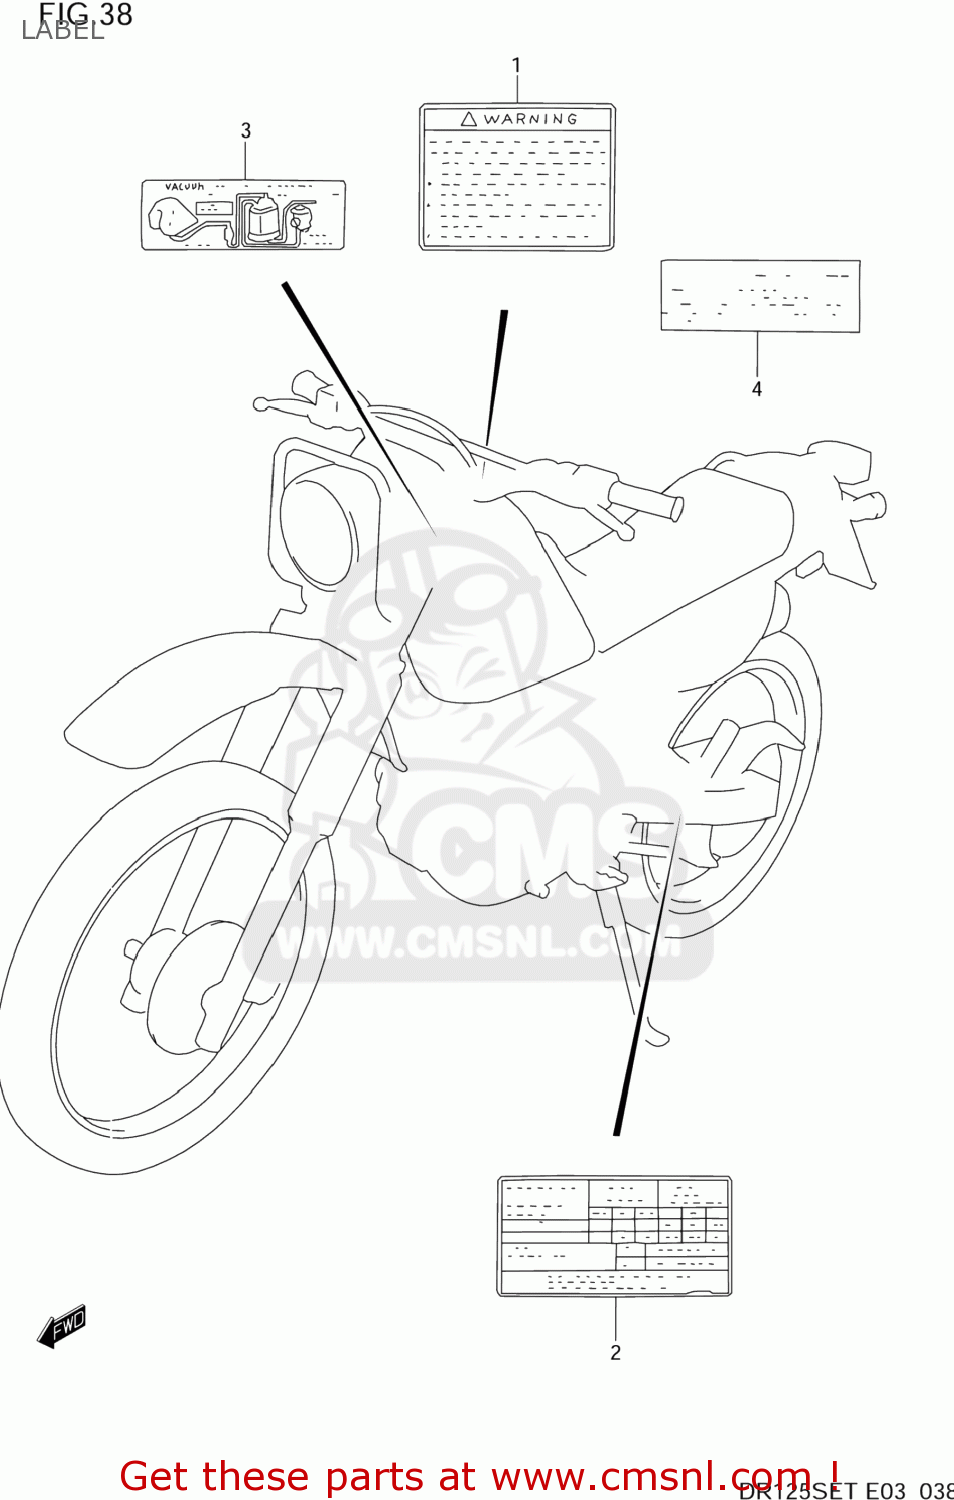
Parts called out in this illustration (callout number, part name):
1	LABEL
2	LABEL,TIRE AIR PRESSURE
3	LABEL,PIPING DIAG
4	LABEL (MANUAL NOTICE)
